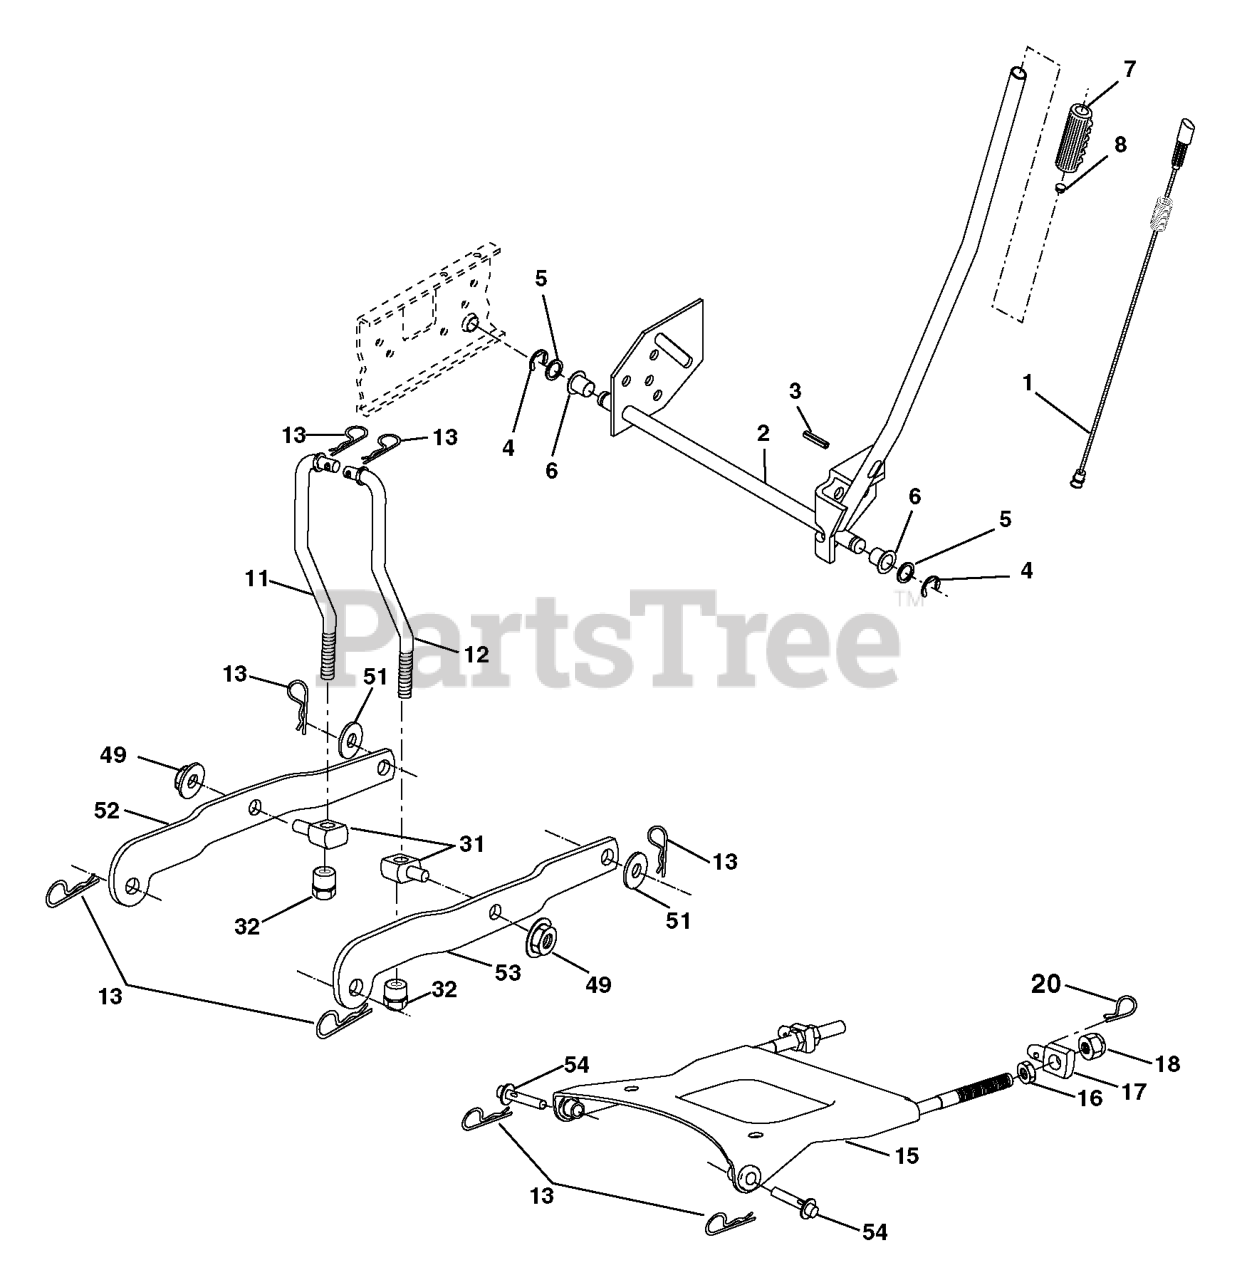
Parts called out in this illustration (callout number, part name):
1	WIRE ASM INNER W/ PLUNGER LT
2	SHAFT ASM R HANDLE
3	PIN GROOVE.
4	RETAINING RING LT
6	BEARING.NYLON
7	GRIP HANDLE
8	PLUNGER BUT KIT
11	LIFT LINK LH
12	LIFT LINK RH
13	RETAINER-SPRNG RB
15	PLATE ASM SUSP FRONT
16	NUT.HEX.JAM.1/2-13
18	NUT.LK.W/WSH.1/2.
20	SPRING RETAINER
32	NUT, LIFT LINK 7/16-20
49	NUT
51	Washer 17/32 x 7/8 x 16 Ga.
52	ARM SUSP. REAR LH
53	ARM SUSP REAR RH
54	PIN.FLANGE
